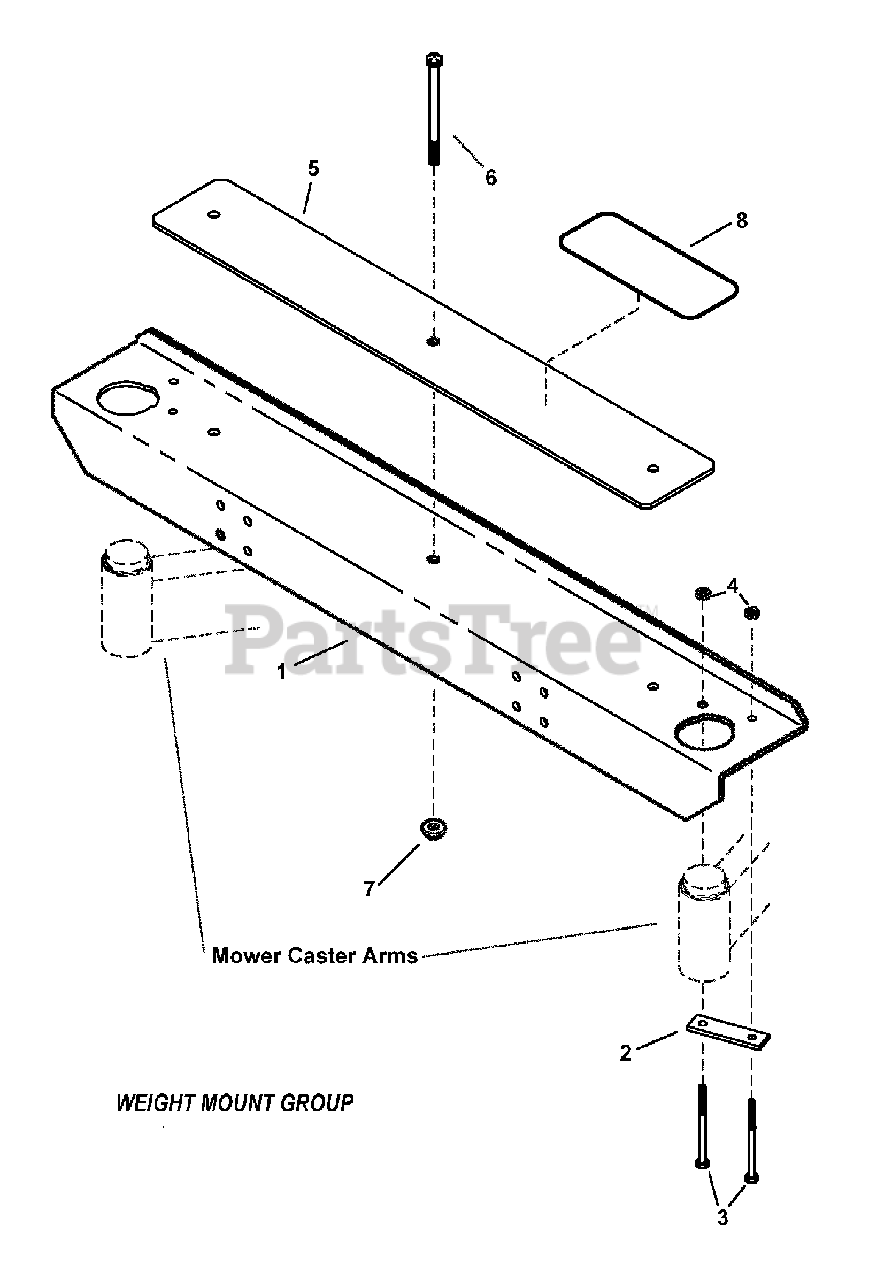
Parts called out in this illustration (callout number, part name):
1	CHANNEL, Weight Mounting
2	BAR, Clamp
3	BOLT, 3/8-16 x 4" Hex Tap, GR5
4	NUT, 3/8-16 Hex Center Lock, GR5 or B
5	BAR, Weight
6	SCREW, 1/2-13 x 4-1/2" Hex Head Cap
7	NUT, 1/2-13 Hex Flange Lock
8	PAD, Anti-Skid, Self-Adhesive
